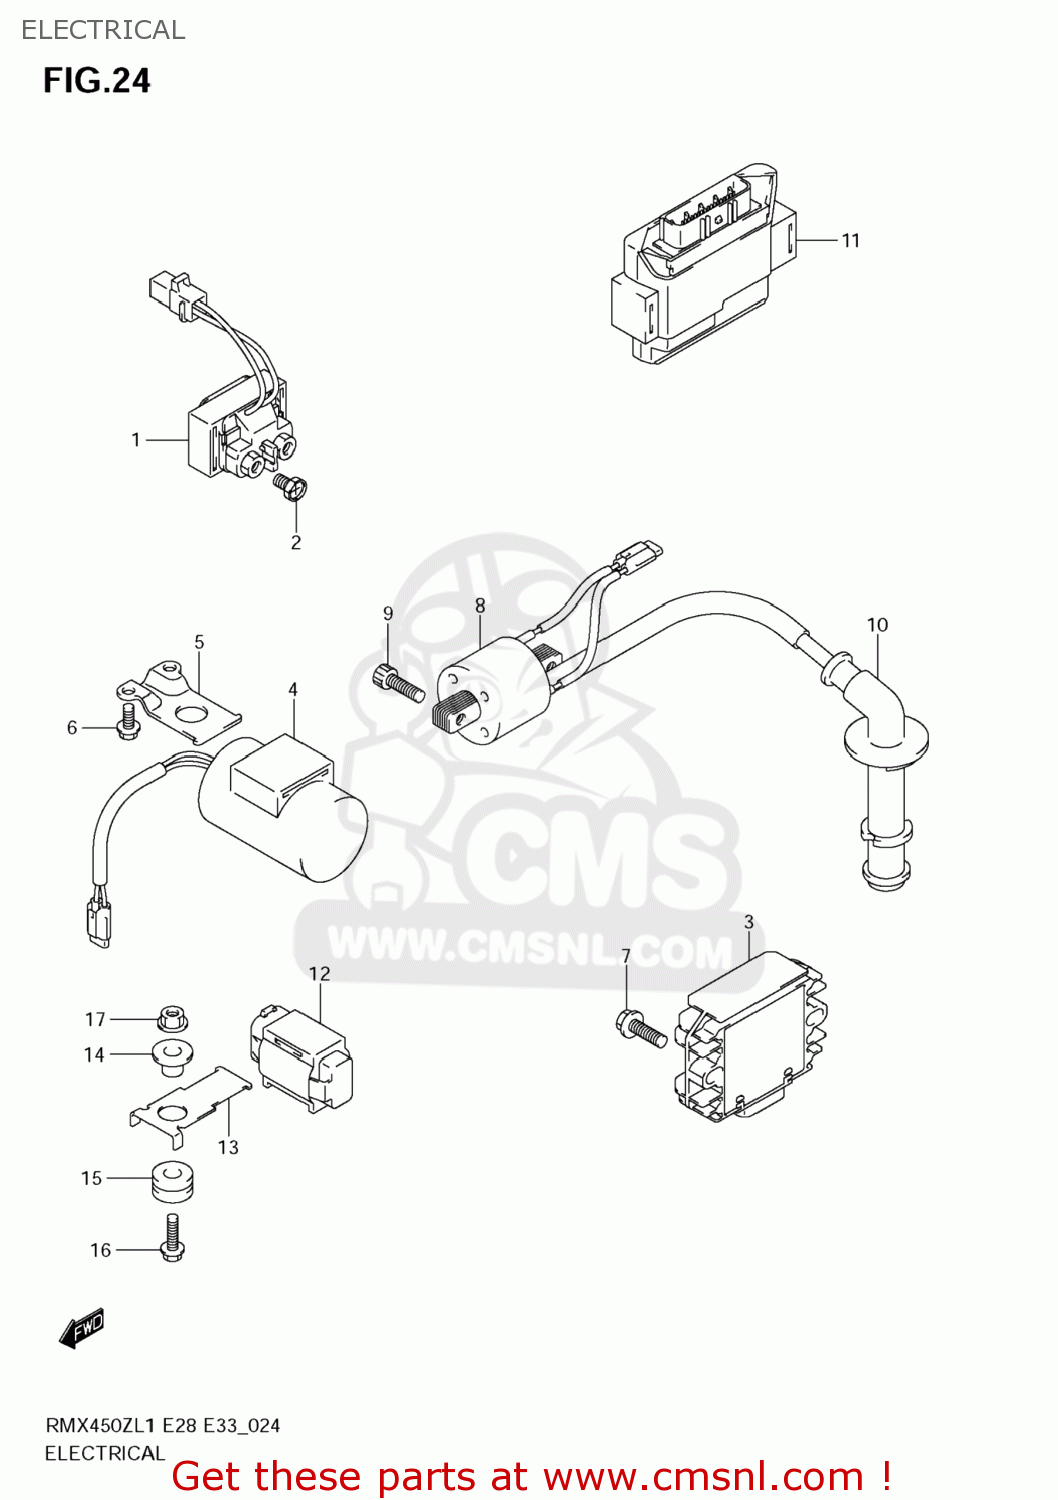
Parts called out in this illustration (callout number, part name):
1	RELAY ASSY,STARTING MOTOR
2	SCREW(6X8)
3	RECTIFIER ASSY
4	CONDENSER ASSY
5	BRACKET,CONDENSER
6	BOLT(6X10)
7	SCREW
8	COIL ASSY,IGNITION
9	BOLT
10	CAP ASSY,SPARK PLUG
11	CONTROL UNIT,FI
12	SENSOR ASSY,FUEL CUT
13	BRACKET,FUEL CUT SENSOR
14	SPACER(6.2X8.4X10.9)
15	CUSHION
16	BOLT
17	NUT
